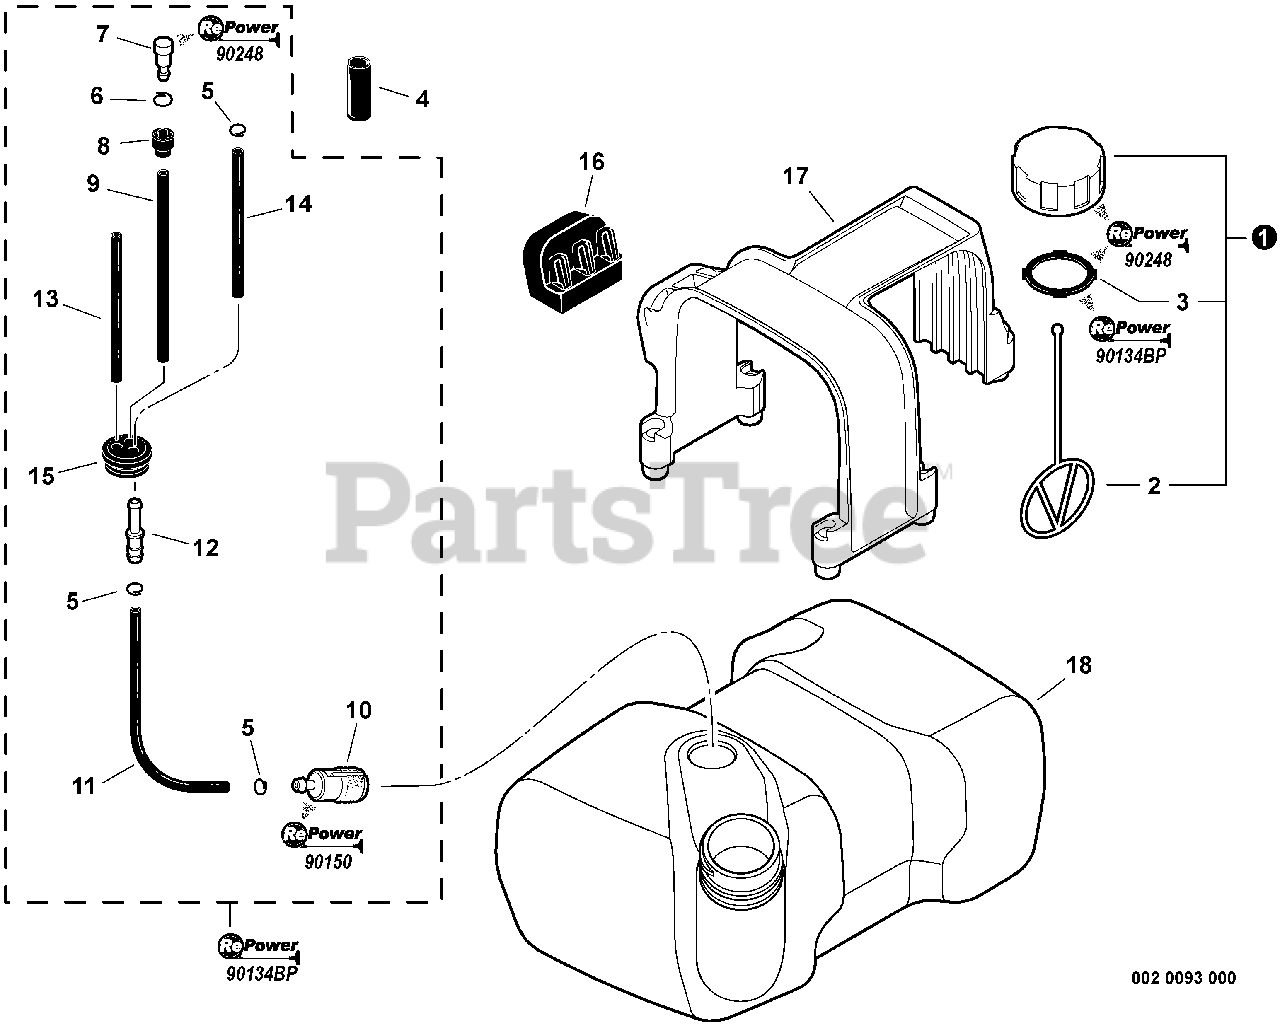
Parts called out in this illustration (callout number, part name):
1	CAP ASSY - ORANGE
2	CONNECTOR, CAP
3	GASKET, CAP
4	SLEEVE
5	CLIP - 6
6	CLIP - 6.5
7	VENT, FUEL TANK
8	COVER, VENT
9	PIPE - 3X6X130 -- BLACK
10	FILTER, FUEL
11	PIPE - FUEL
12	CONNECTOR, PIPE
13	PIPE - 2.4X5X200 -- BLACK
14	PIPE - 3X5X135 -- BLACK
15	GROMMET
16	CUSHION
17	GUARD, FUEL TANK
18	TANK, FUEL
19	RePower FUEL SYSTEM KIT
20	Repower TUNE-UP KIT
21	Repower CAP AND VENT KIT
